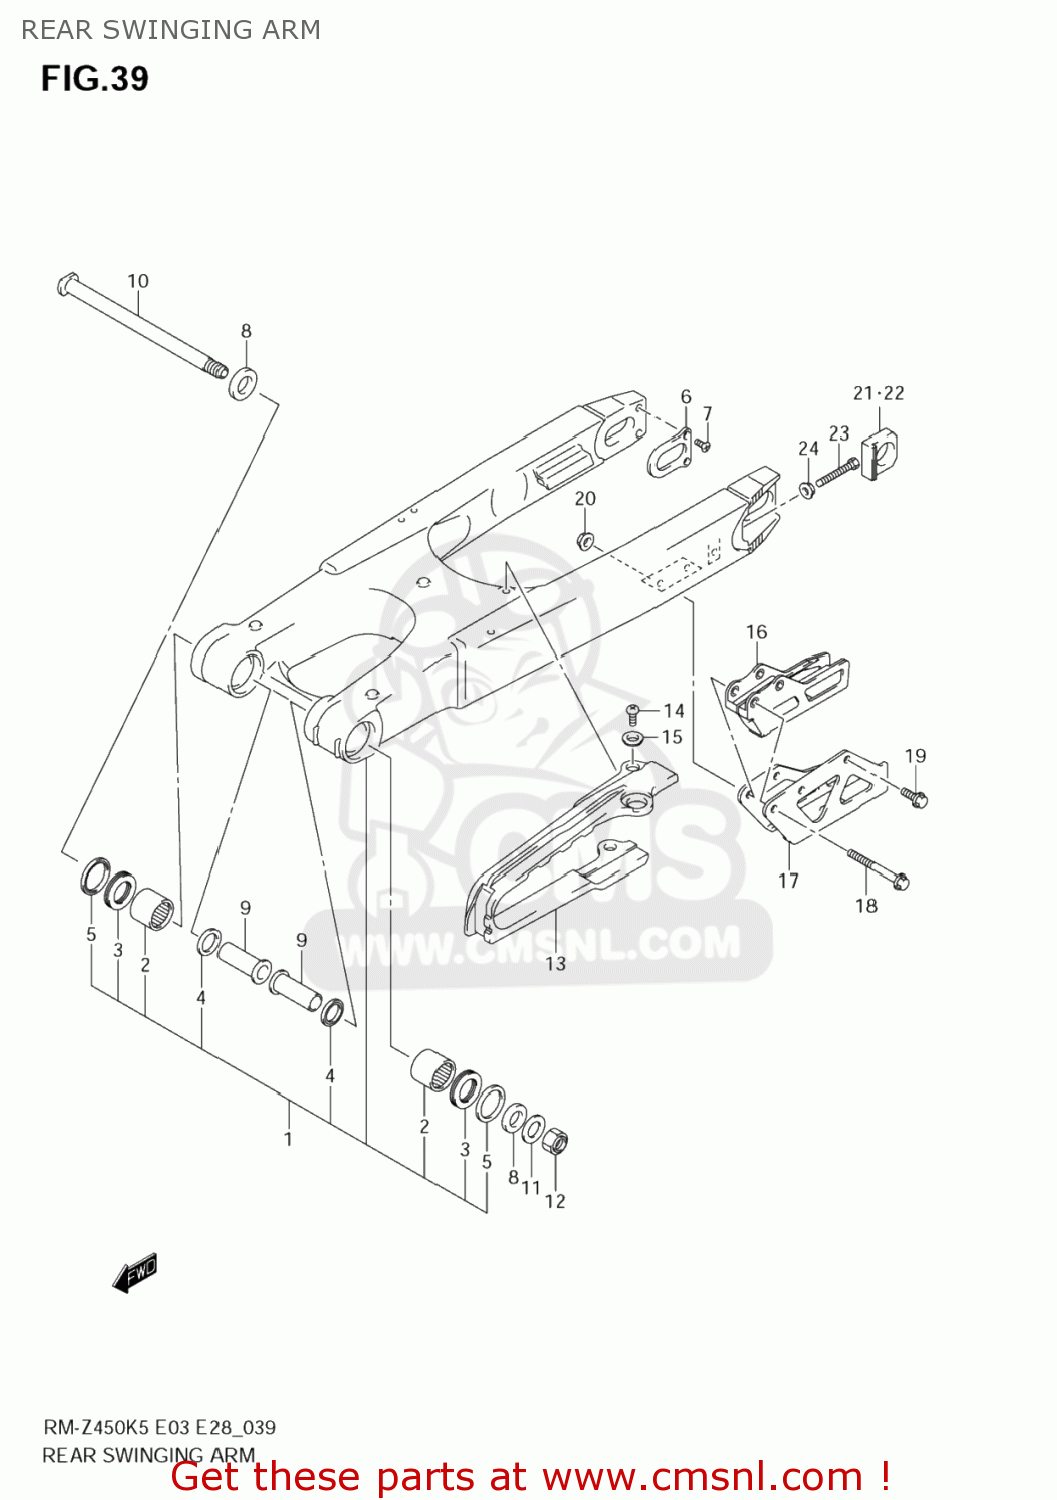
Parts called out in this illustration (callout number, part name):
1	SWINGINGARM ASSY,RR
2	BEARING(22X29X30)
3	BEARING(22X35X2)
4	SEAL,OIL(22X29X4)
5	SEAL,RR SWGARM PIVOT OUTER
6	PLATE,SWING ARM RR
7	SCREW,UPPER
8	SPACER,RR SWGARM PIVOT OUTER
9	SPACER,SWGARM PIVOT INNER
10	SHAFT,RR SWINGINGARM PIVOT
11	WASHER, FIXED DRIVE FACE
12	NUT
13	BUFFER,CHAIN TOUCH DEFENSE
14	SCREW
15	WASHER
16	GUIDE,CHAIN
17	PLATE,CHAIN GUIDE
18	BOLT(6X45)
19	BOLT(6X12)
20	NUT
21	WASHER,CHAIN ADJUSTER,R
22	WASHER,CHAIN A
23	BOLT(8X50)
24	NUT
